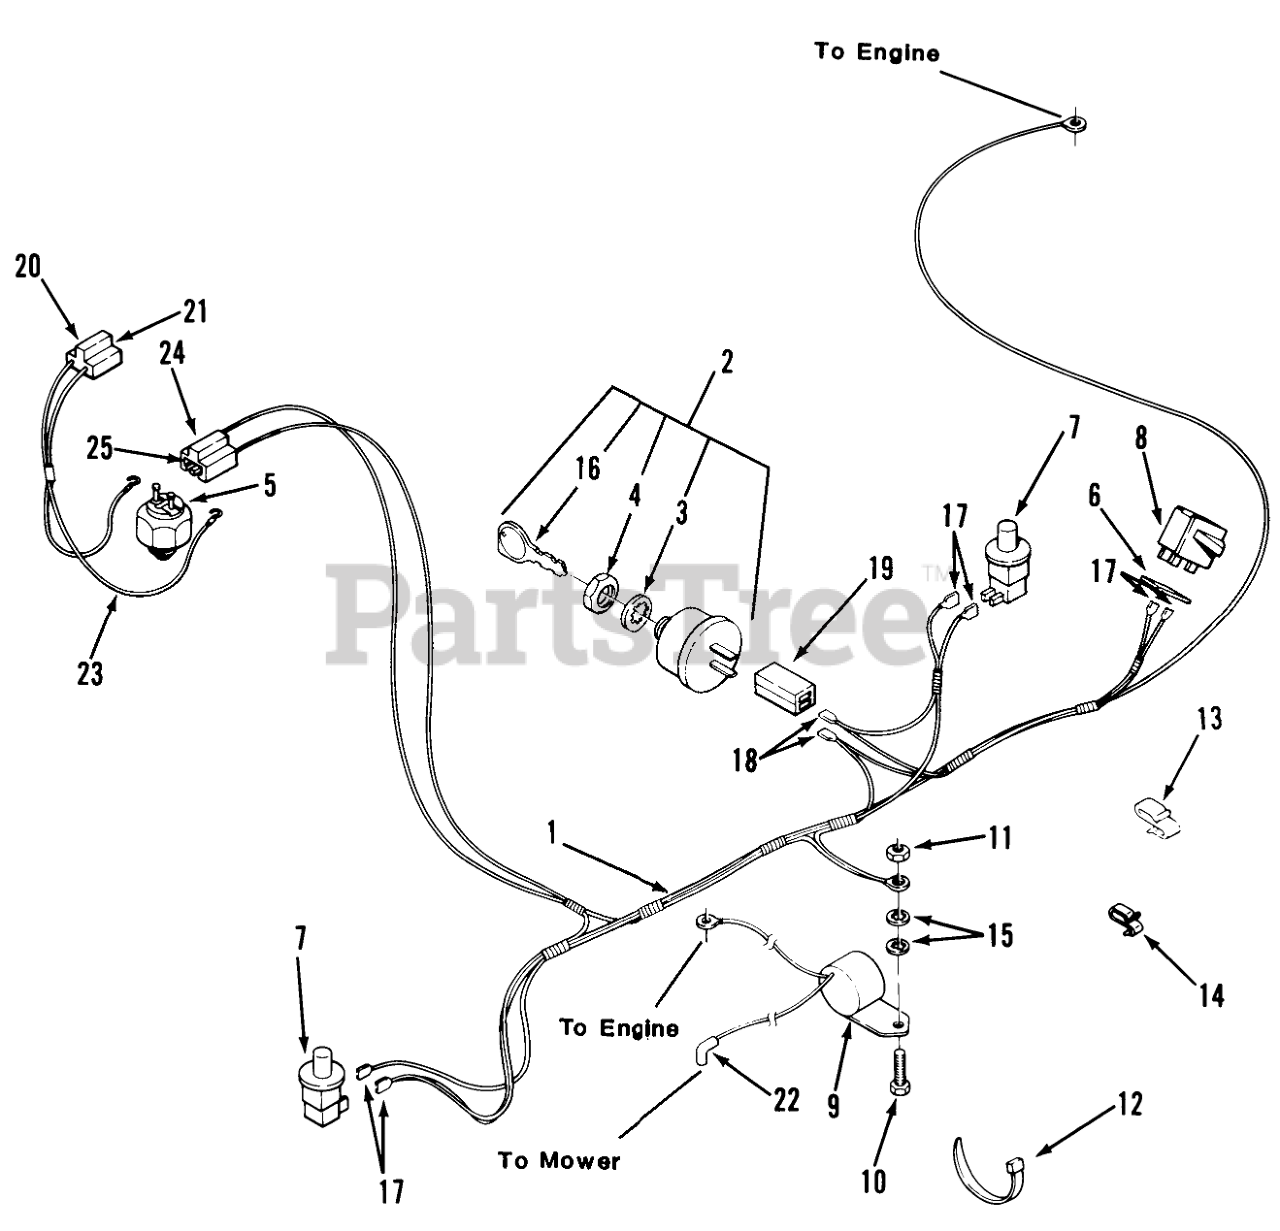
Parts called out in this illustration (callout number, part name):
1	WIRING HARNESS
2	SWITCH IGNITION
3	LOCKWASHER
5	SWITCH SAFETY
6	SHIELD-DIRT SPST
7	SWITCH (N.C.)
8	SWITCH
9	INTERLOCK MODULE
10	Screw
11	Nut
12	PLASTIC TIE
13	CLIP-CABLE
14	SPEED CLIP
15	Washer-Lock
16	Ignition Key
17	Terminal
18	TERMINAL-TAB RCPT
19	Conn. Body-Part of 2
20	CONNECTOR BODY B
21	TERMINAL-TAB RCPT
22	Terminal Part of 5
23	ASSY WIRING HARNESS
24	WHEEL ASM
25	Connector Part of 5
